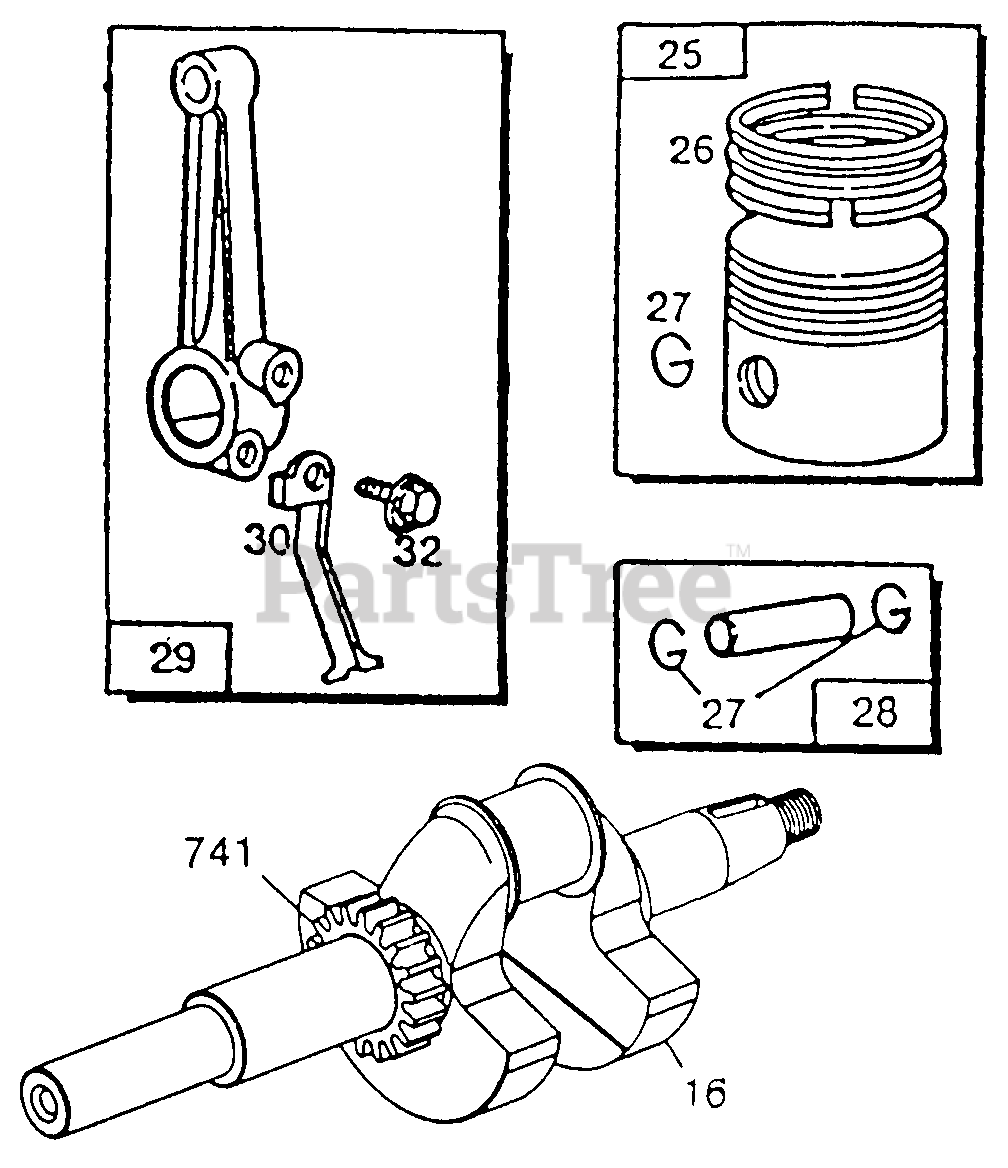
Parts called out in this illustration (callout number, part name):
16	Crankshaft
25	Piston Ass'y.--Std.
26	Ring Set--Std. Piston
27	Lock--Piston Pin
28	Pin Ass'y.--Piston (Std.)
29	Rod Ass'y.--Conn.
30	Dipper--Conn. Rod
32	Screw--Conn. Rod
741	Gear--Timing
